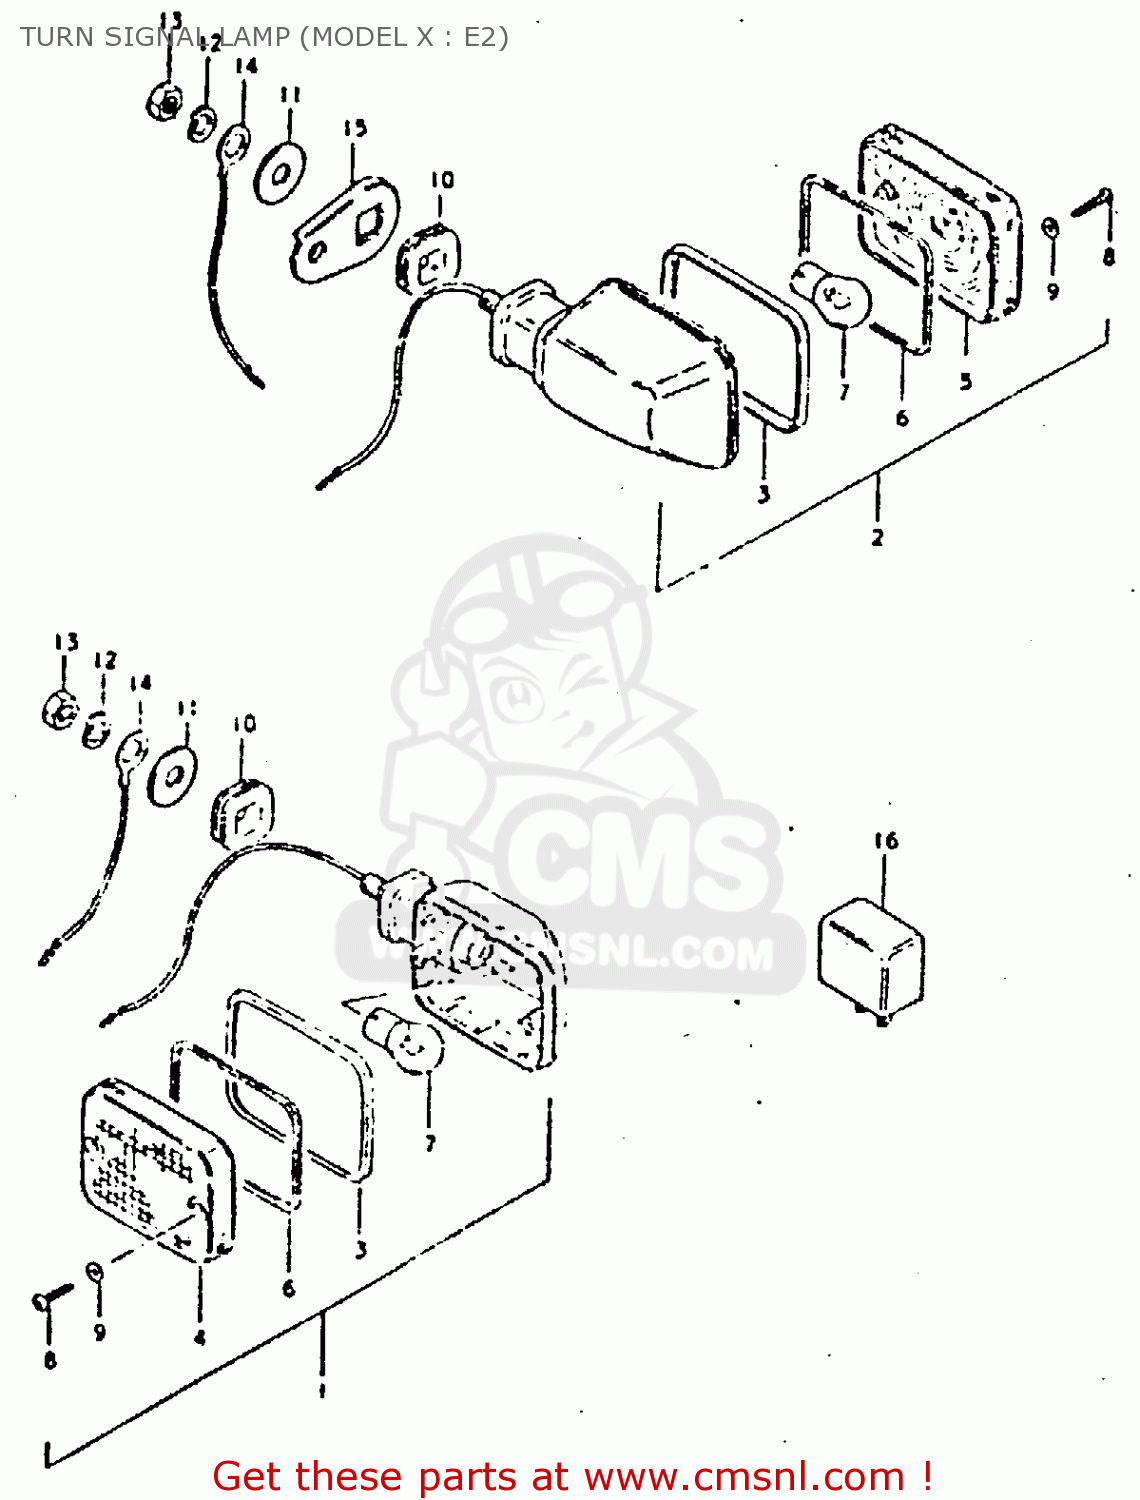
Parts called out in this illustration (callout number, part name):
1	LAMP, FRONT TURN SIGNAL
2	LAMP, REAR TURN SIGNAL
3	RIM
4	LENS
5	LENS
6	GASKET (NAS)
7	BULB 12V 21W
8	SCREW
9	GASKET (NAS)
10	CUSHION
11	WASHER (10.5X30X2.3)
12	LOCK WASHER
13	NUT
14	LEAD WIRE,EARTH
15	BRACKET,RR TURN SIGNAL LAMP
16	RELAY,TURN SIGNAL
